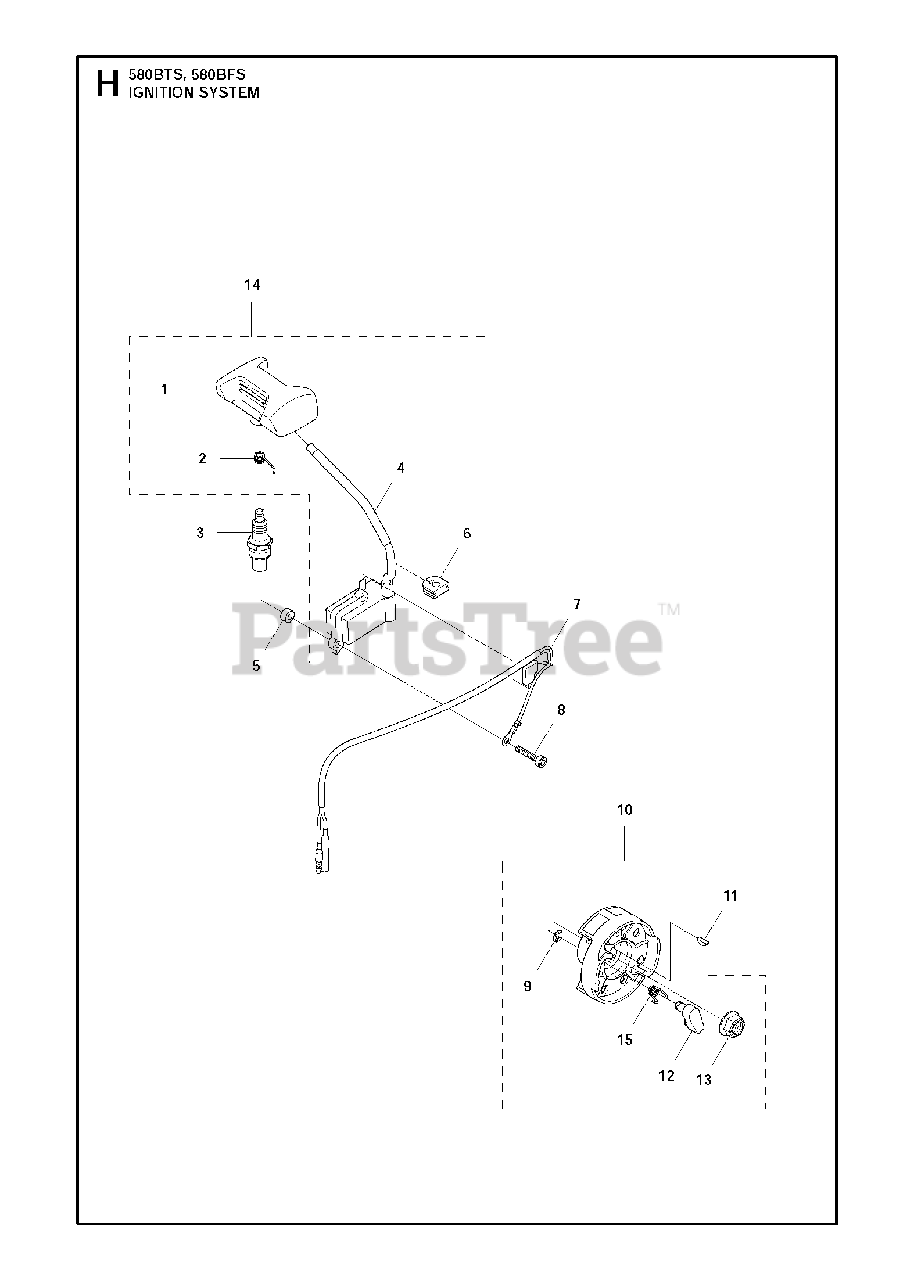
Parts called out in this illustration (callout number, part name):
1	SPARK PLUG CAP
2	SPRING PLUG
3	PLUG CMR7H
4	TUBE
5	SPACER
6	GROMMET
8	BOLT TORX
9	RING
10	ROTOR ASSY
12	RATCHET
13	NUT
14	COIL ASSY
15	SPRING
